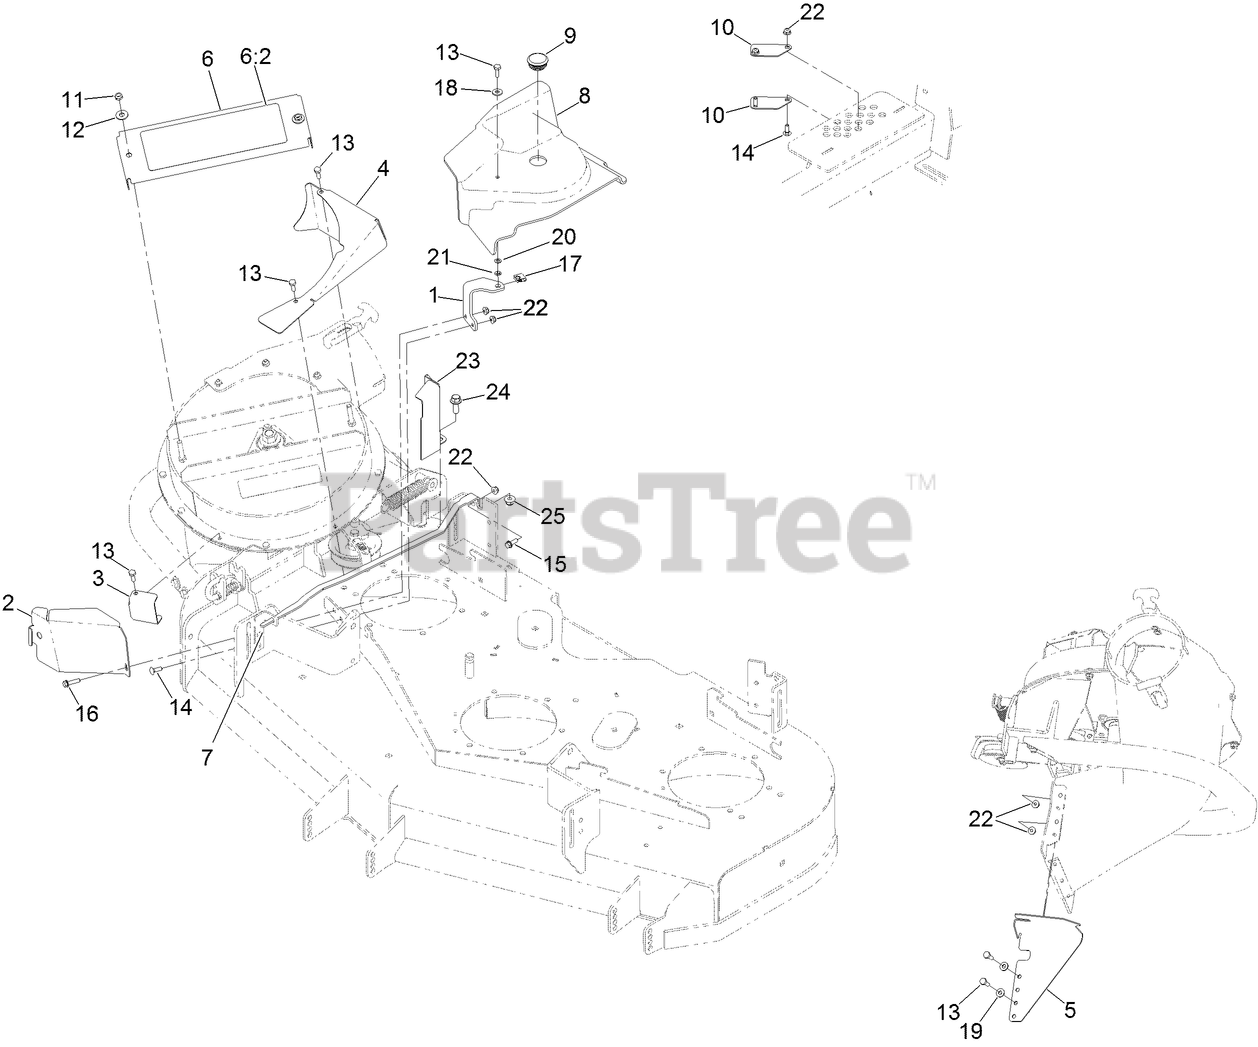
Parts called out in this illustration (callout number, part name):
1	BRACKET-COVER, BELT
2	GUARD-BAGGER
3	GUARD-FRONT, LEFT
4	GUARD-TOP
5	GUARD-BAGGER
6	COVER-BEARING
6:2	DECAL-DANGER
7	BRACKET-SKIRT, LOWER
8	COVER-BELT, TE
9	PLUG-PLASTIC
10	PLATE-COVER, HOC [BLACK]
11	NUT-LOCK, NI
12	WASHER-FLAT
13	SCREW-HH
14	BOLT-CARR
15	SCREW-HHF
16	SCREW-HHF
17	NUT-SPEED
18	WASHER-FLAT
19	WASHER-FLAT
20	WASHER-FLAT
21	PUSHNUT-RETAINER, BOLT
22	NUT-HF
23	GUARD-REAR
24	SCREW-HHF
25	NUT-HF, NI
